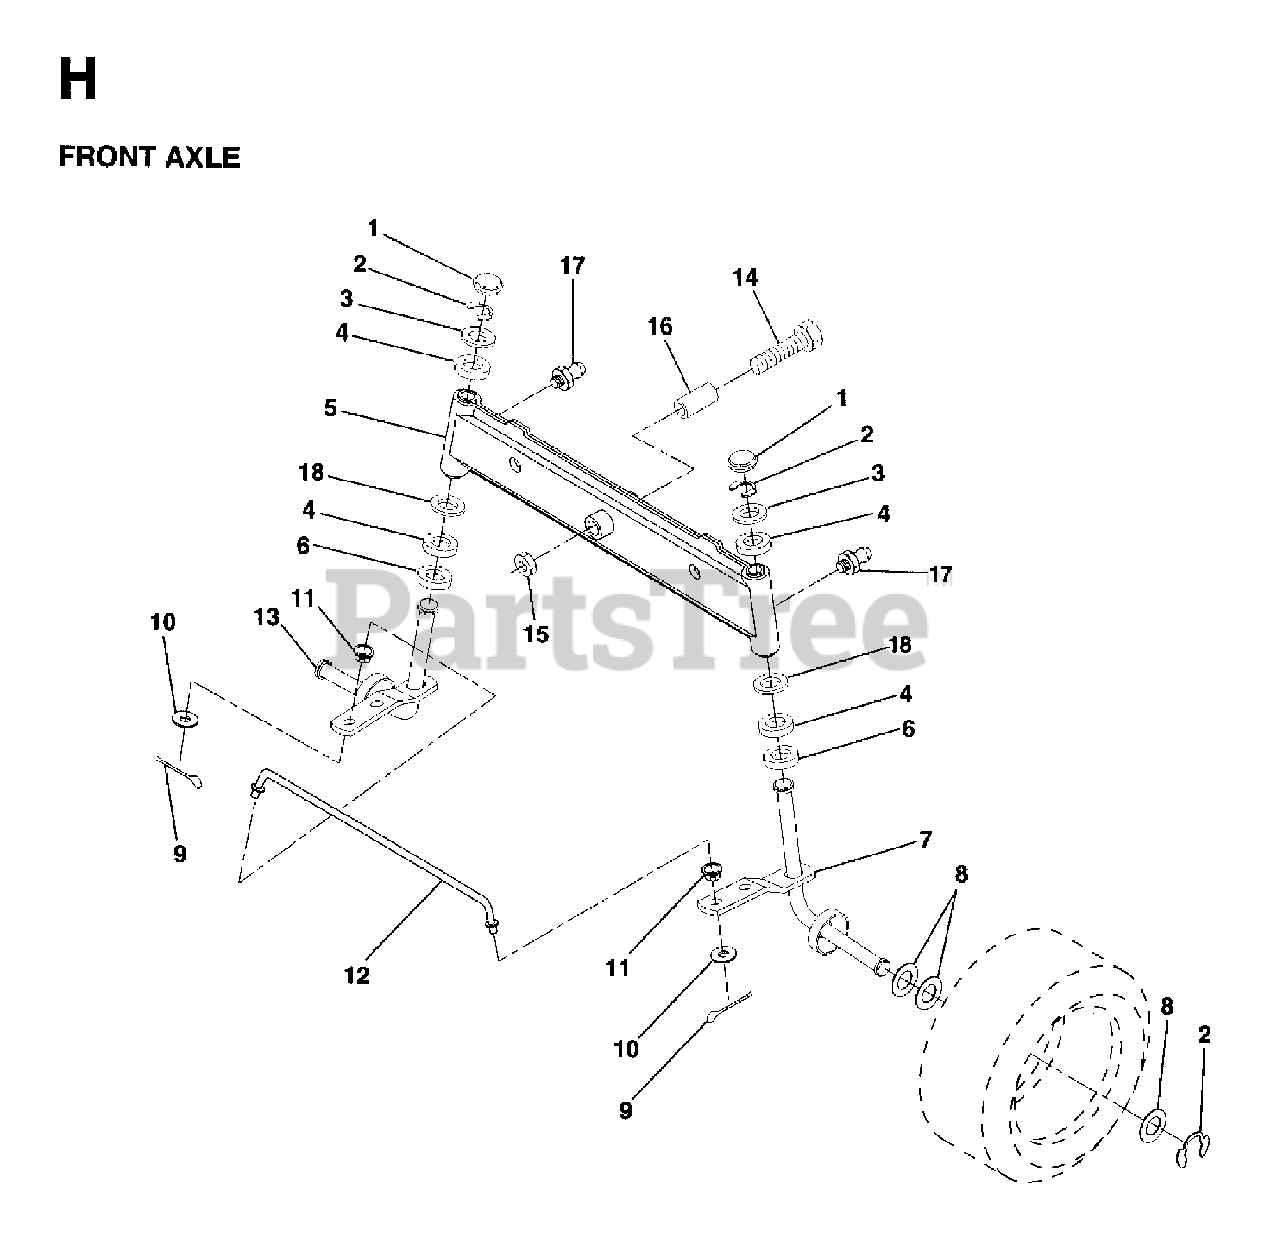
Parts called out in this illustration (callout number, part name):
1	CAP.SPINDLE
2	RING CLIP
4	BRNG T
5	AXLE ASSY
7	SPINDLE ASSY RH NLA
9	COTTER PIN
11	BUSHING.DRAGLINK
12	TIE ROD
13	SPINDLE ASSY LH
14	BOLT.HEX.5/8-11
15	NUT-LOC,FLANGE LT
16	BEARING
17	ZERK M
